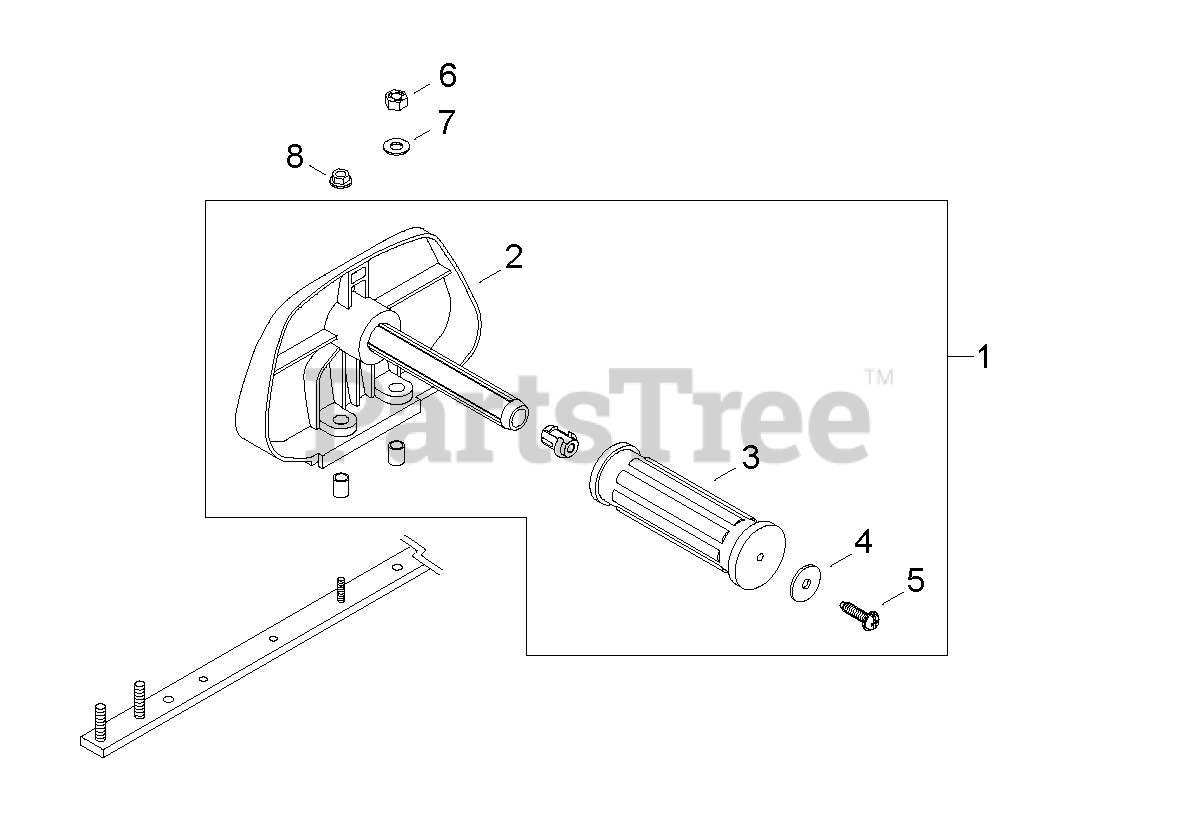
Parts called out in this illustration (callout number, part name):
1	HANDLE ASSY, FRONT
2	HANDLE, FRONT
4	WASHER 5 MM
5	SCREW 5×20
7	WASHER 6.5×13×1
8	NUT, FLANGE M5
